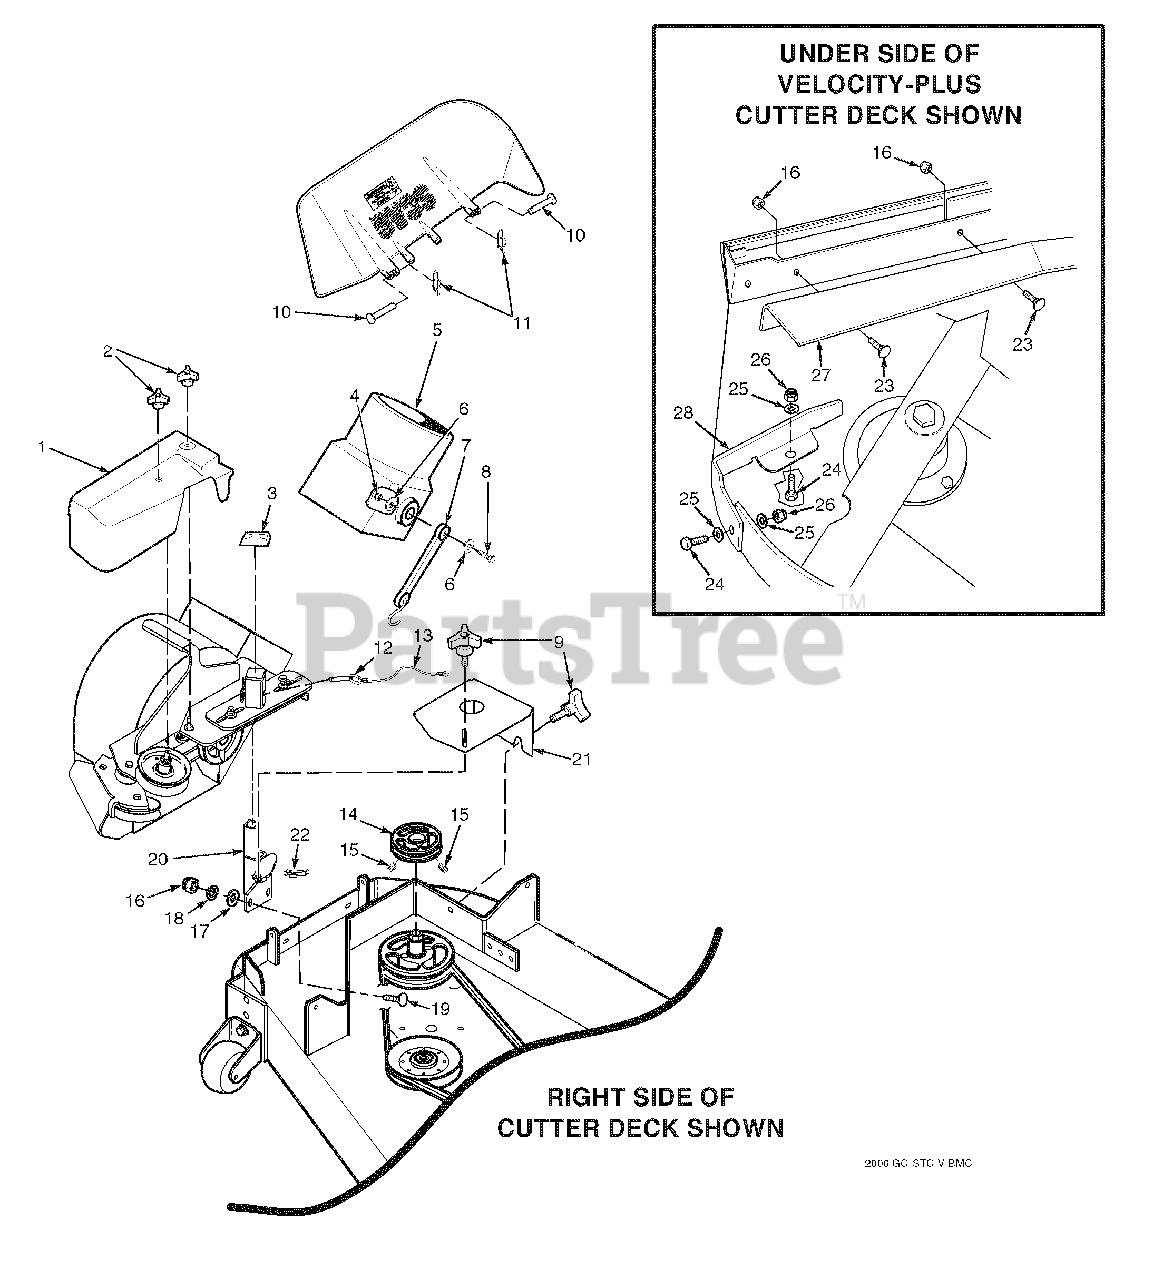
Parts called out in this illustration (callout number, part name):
1	Belt Cover, GC-STC
2	Wingnut, Plastic 3/8" Small
3	Cap, Square Vinyl
4	Nut, Elastic Stop 1/4-20
5	Adapter, Blower GC-STC
6	Flatwasher, 1/4-.312 x .750 x .065
7	Rubber Strap 7-3/4"
8	Bolt, Hex Head 1/4-20 x 1-1/4"
9	Knob W/Stud, 3/8-16 x 1-1/4"
10	Clevis Pin, 5/16 x 1-1/2"
11	Pin, Rue Cotter 5/16 Dia.
12	Pin, Ring 1/2 x 2-1/4"
13	Lanyard
14	Pulley, 4.0" Dia. 1.125 Bore
15	Setscrew, 5/16-18 x 3/8"
16	Nut, Elastic Stop 3/8-16
17	Lockwasher, 3/8"
18	Flatwasher, 3/8-.391 x .938 x .105
19	Bolt, Carr. 3/8-16 x 1-1/4" Grade 5
20	Mounting Post Weldment, Blower
21	Belt Cover, GC-STC-48V
23	Bolt, Carriage 3/8-16 x 1"
24	Bolt, Hex Head 5/16-18 x 1"
25	Flatwasher, 5/16-.375 x .875 x .083
26	Nut, Elastic Stop 5/16-18
27	Baffle, Front 48" Deck
28	Baffle, Turbo 48" Deck
